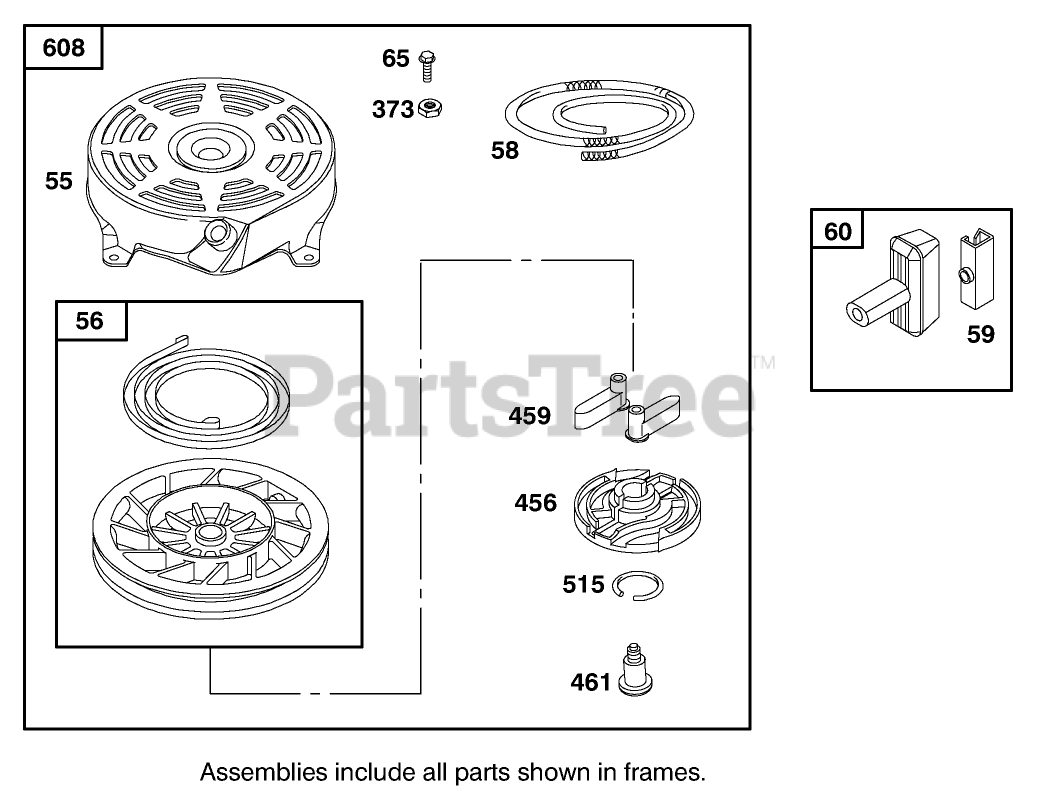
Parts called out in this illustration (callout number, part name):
56	PULLEY-STARTER, REWIND
58	ROPE-STARTER
59	INSERT-HANDLE, REWIND
65	SCREW-HH
373	NUT-HEX
456	RETAINER-STARTER, REWIND
459	PAWL-STARTER
515	SPRING-TORSION
608	REWIND ASM
